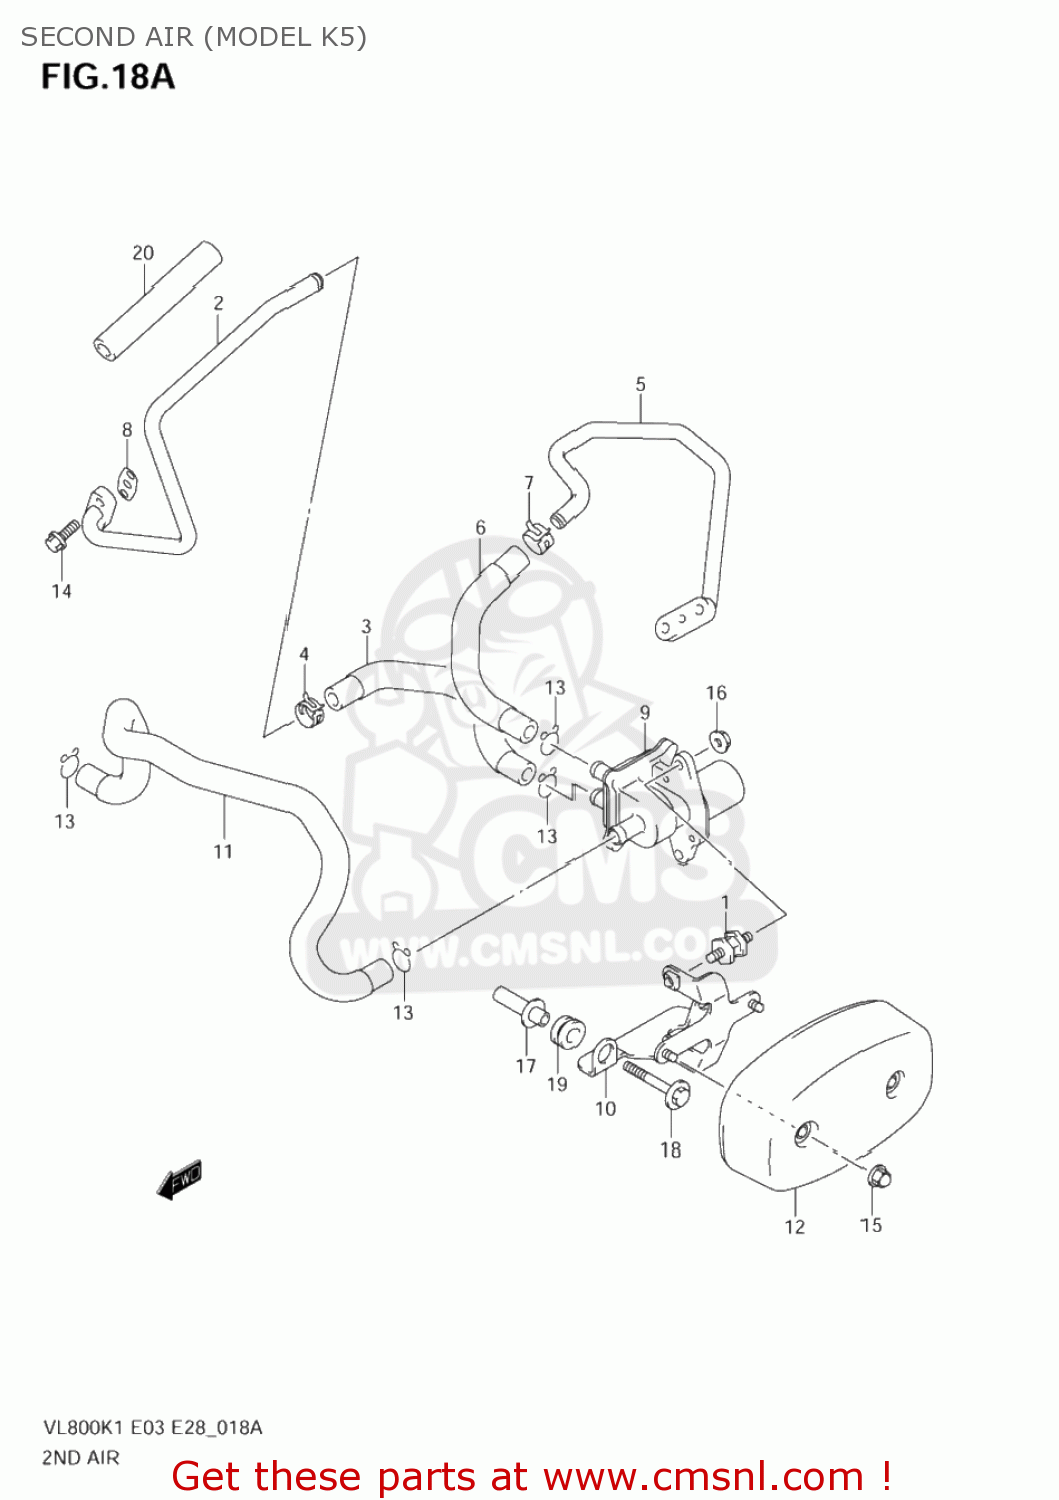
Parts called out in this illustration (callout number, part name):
1	BOLT,CUSHION
2	PIPE,2ND AIR FR
3	HOSE,2ND AIR VALVE FR
4	CLIP
5	PIPE,2ND AIR RR
6	HOSE,2ND AIR VALVE RR
7	CLIP
8	GASKET,2ND AIR PIPE (NAS)
9	VALVE ASSY,2ND AIR
10	BRACKET,2ND AIR SPRT
11	HOSE,2ND AIR CLEANER
12	COVER,2ND AIR VALVE
13	CLIP
14	BOLT
15	NUT
16	NUT
17	SPACER,2ND AIR SPRT BRKT
18	BOLT(6X55)
19	CUSHION
20	PROTECTOR,2ND AIR PIPE FR
